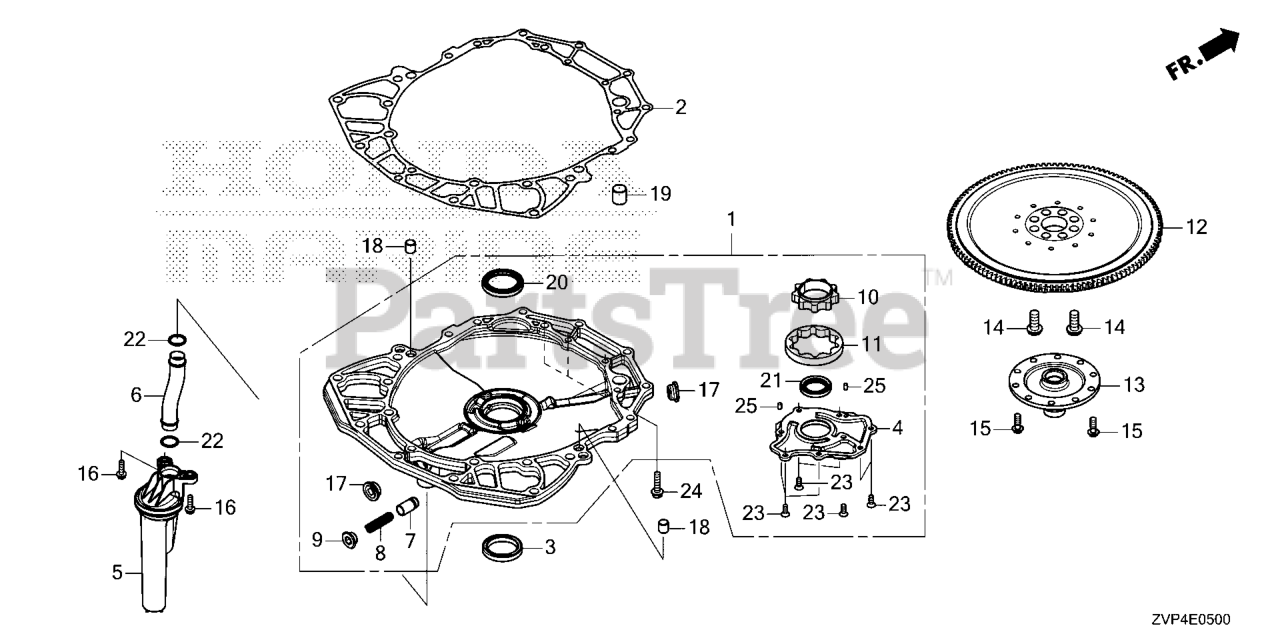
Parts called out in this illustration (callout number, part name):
1	PUMP ASSY., OIL
2	PKG, OIL PUMP BODY
3	RUBBER, OIL PUMP
4	COVER, OIL PUMP
5	STRAINER COMP, OIL
6	PIPE, OIL STRAINER
7	VALVE, RELIEF
8	SPRING, RELIEF VALVE
9	BOLT, SEALING (18MM)
10	ROTOR, OIL PUMP (INNER)
11	ROTOR, OIL PUMP (OUTER)
12	FLYWHEEL COMP
13	BOSS, FLYWHEEL
14	BOLT (12MM)
15	BOLT, SPECIAL (8MM)
16	BOLT, FLANGE (6X22)
17	BOLT, SEALING (22MM) (NOT AVAILABLE)
18	PIN, DOWEL (14X15)
19	PIN, DOWEL (20X22)
20	OIL SEAL (46X60X9)
21	OIL SEAL (31X46X7) (NOK)
22	O-RING (20.6X2.6)
23	SCREW, FLAT (6X16) (YAMADA)
24	BOLT, FLANGE (8X32)
25	ROLLER (5X8)
